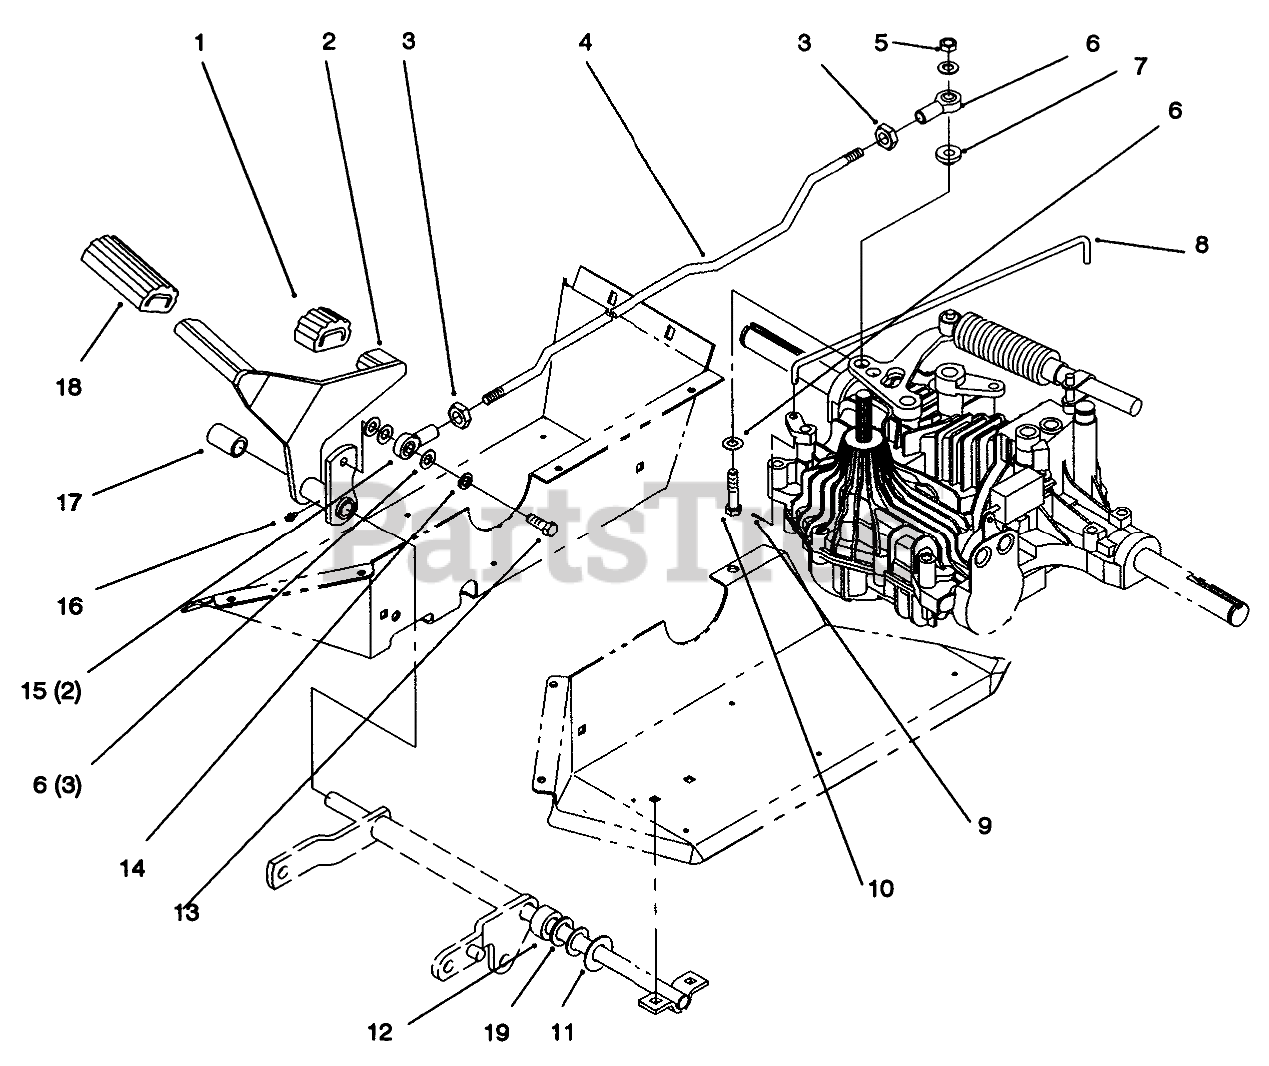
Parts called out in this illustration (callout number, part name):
1	PAD-PEDAL
2	Pedal-Hydro
3	NUT-HJ
4	ROD - HYDRO
5	NUT-LOCK, NI
6	WASHER-FLAT
7	BUSHING
8	ROD - BYPASS
9	PIN-COTTER
10	SCREW-HH
11	WASHER
12	SPACER
13	SCREW-HH
14	WASHER-LOCK
15	END-ROD, FEMALE
16	FITTING-GREASE
17	SPACER
18	PAD-PEDAL
19	WASHER-FLAT
